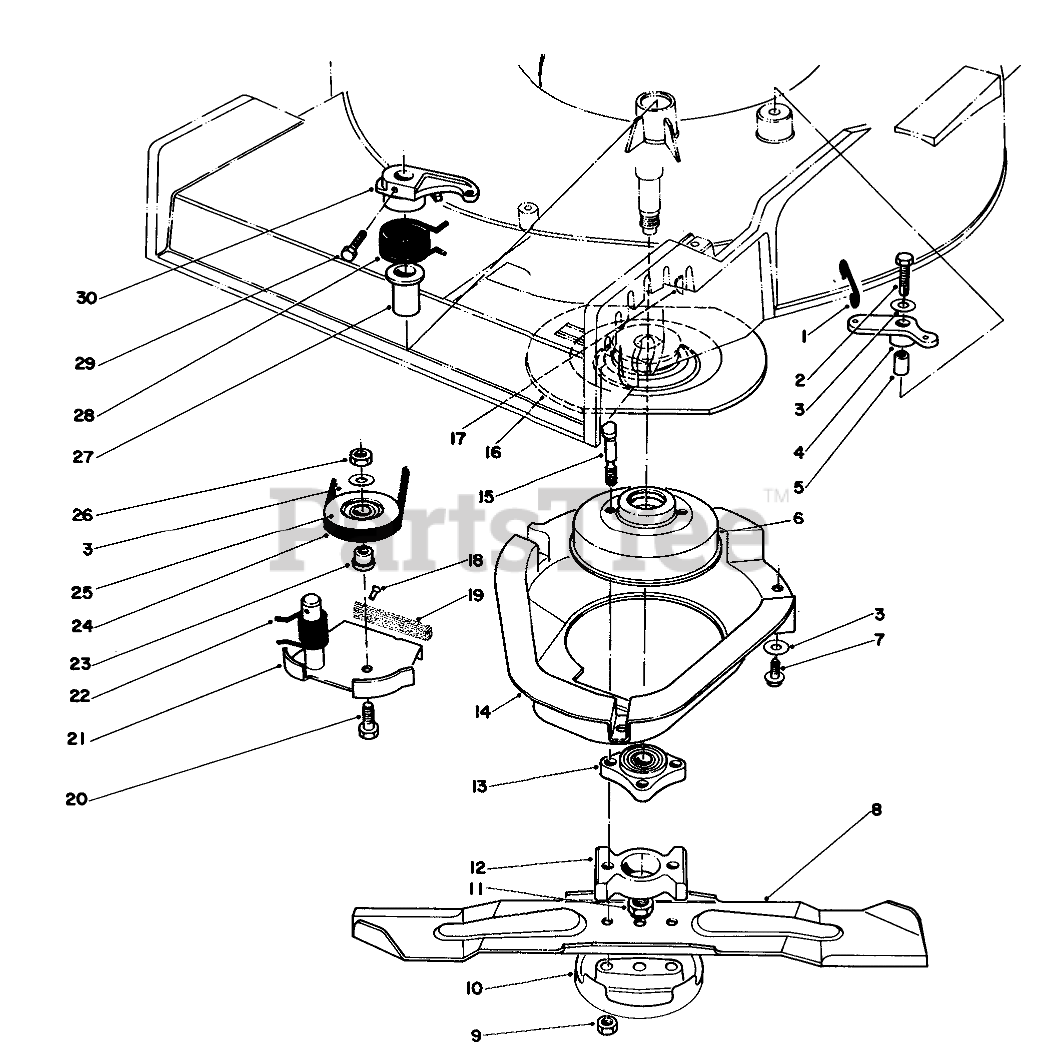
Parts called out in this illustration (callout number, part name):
1	Link Control
2	SCREW-HH
3	WASHER-PLAIN
4	Bell Crank
5	Sleeve-Bell Crank
6	Brake Drum
7	SCREW-HWHTF
8	BLADE-21in
9	Nut
10	Anti Scalp Cup
11	NUT-LOCK, NI
12	Spacer Blade
13	HUB ASM
14	SHIELD BBC
15	BOLT-BLADE
16	Flywheel
17	KEY-WOODRUFF
18	.185 DIA X .375 RT +
19	Paid
20	SCREW-HH
21	Brake Plate
22	SPRING-TORSION
23	HUB-PULLEY, IDLER
24	V-Belt
25	PULLEY-IDLER
26	NUT-LOCK, NI
27	BUSHING PM
28	TORSION SPRING
29	SCREW-HH
30	Lever
